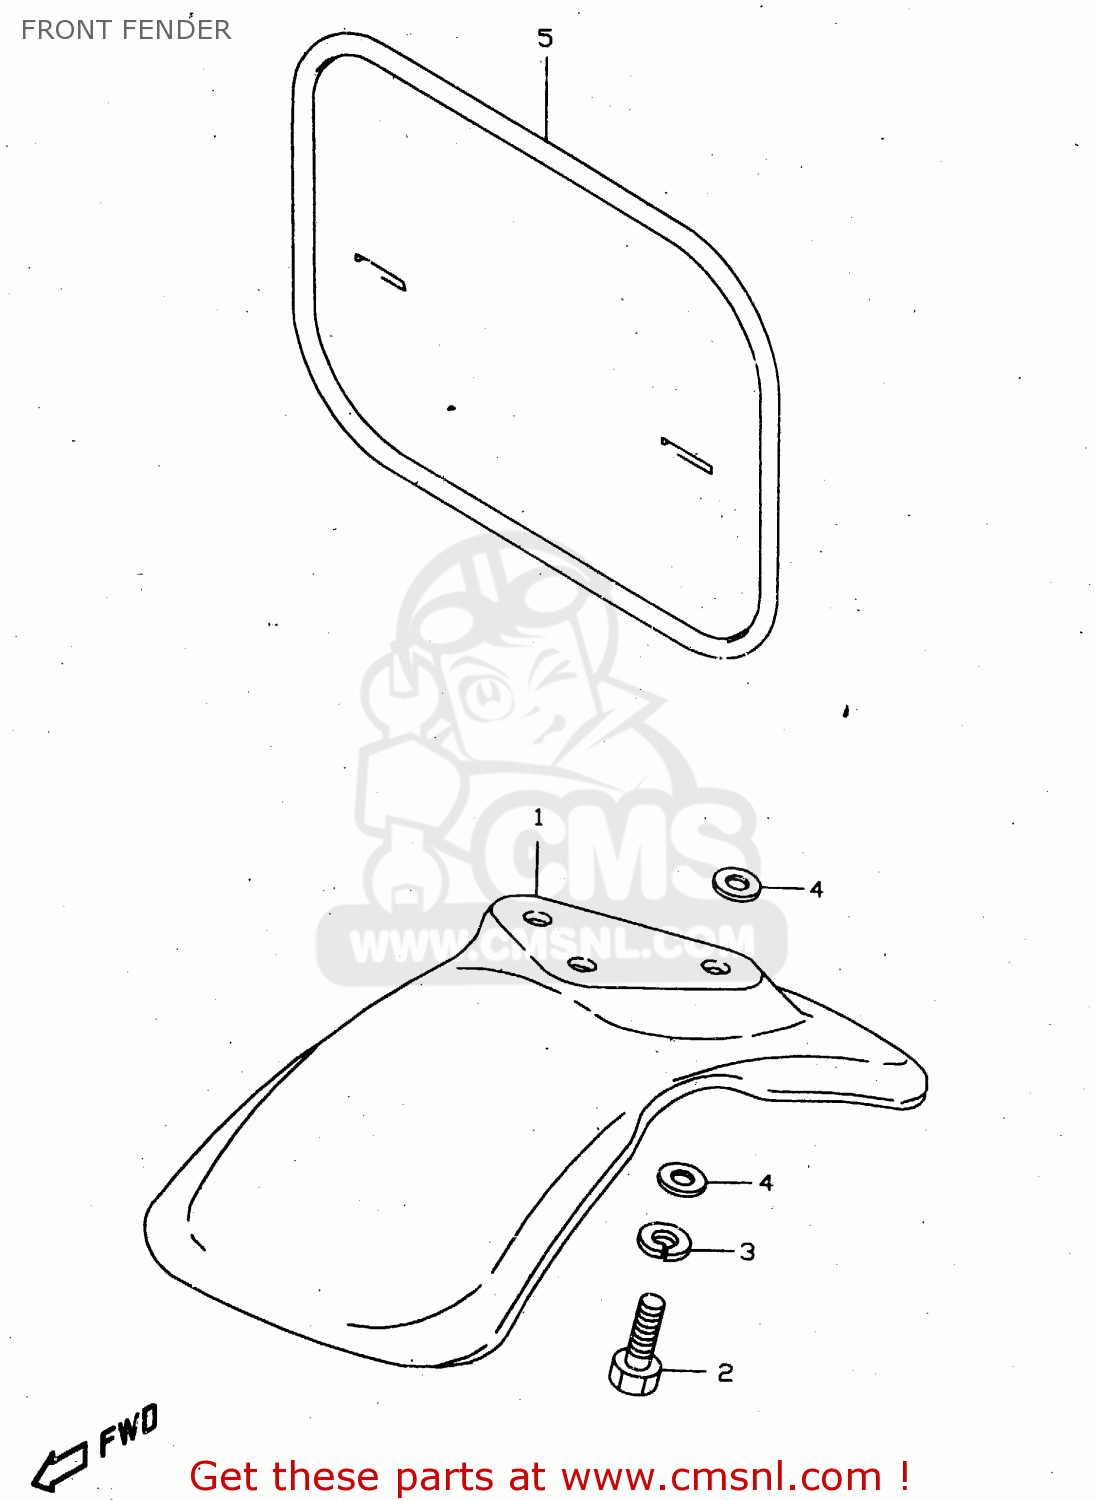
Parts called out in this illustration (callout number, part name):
1	FENDER,FR
2	BOLT
3	LOCK WASHER
4	WASHER(6.5X18X1)
5	PLATE,NUMBER FR
